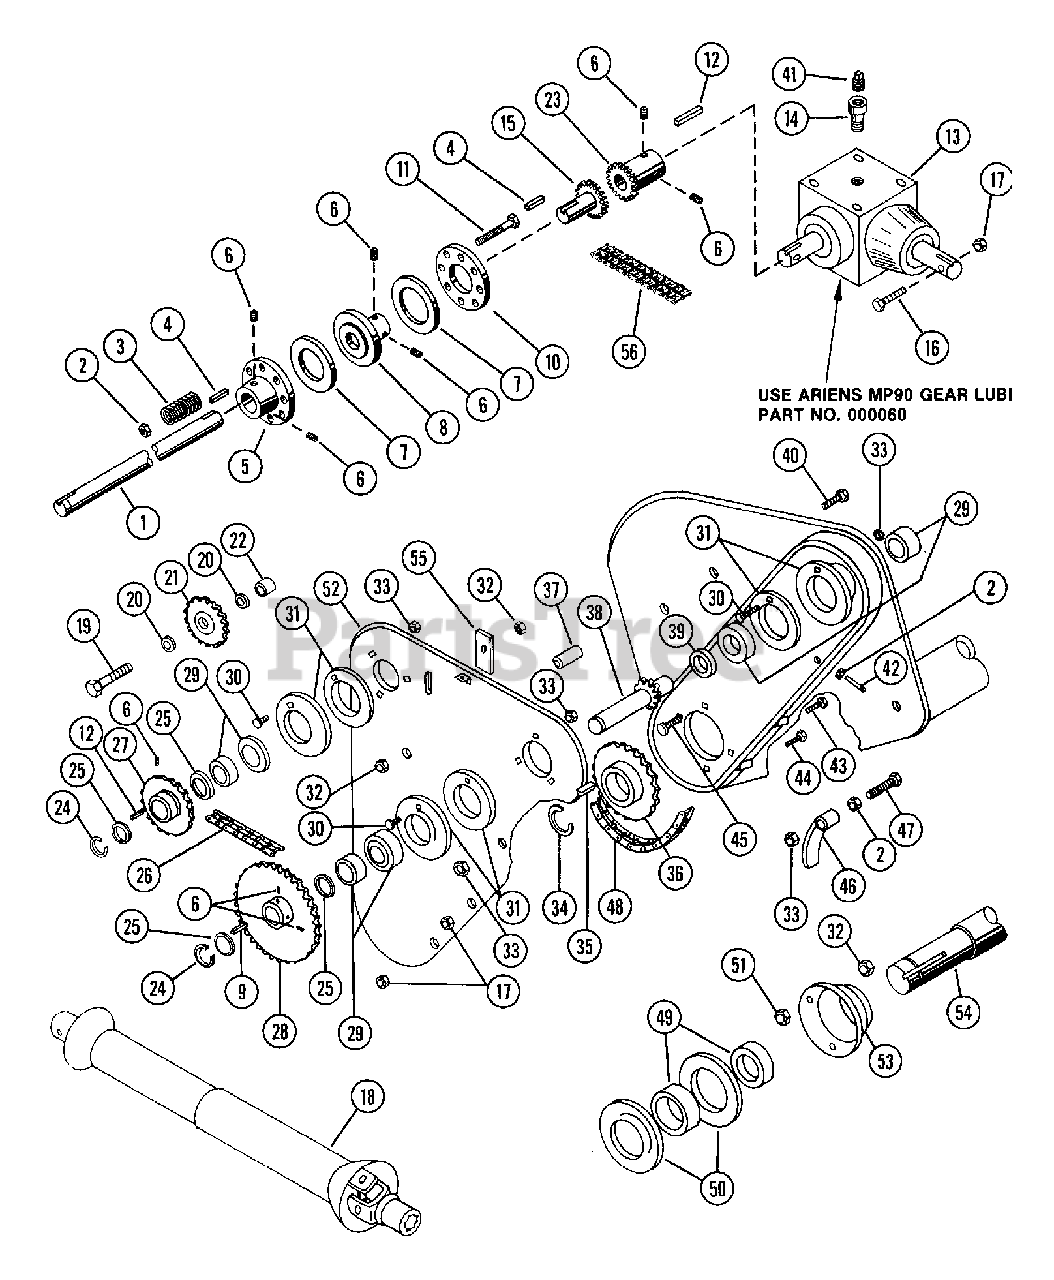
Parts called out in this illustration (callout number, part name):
1	DRIVE SHAFT
2	NUT-HEX .312-18
3	SG-COMP .135X.66X.75 WLD210
4	KEY-SQ .25 X 1.25 X .25 SAE
5	HUB-END PLATE
6	SCR-SET .32-18X.50 SKH
7	CLUTCH DISC
8	HUB-CENTER
9	KEY-SQ .25X1.0X.25 SAE 8630
10	PRESSURE PLATE
11	BLT-HEX .31-18X2.75 GR5
12	KEY-SQ .25 X 1.50 X .25 SAE
13	GEAR BOX ASSEMBLY
14	COUPLING
15	COUPLER-MALE HALF
16	BLT-HEX .38-16X2.50 PL GR5
17	NUT-LK TOP .375-16 GR C YWZC
18	UNIVERSAL DRIVE SHAFT
19	BLT-HEX .50-13X2.75 PL GR5
20	WSHR-FL-STL .505X1.000X.062
21	IDLER SPROCKET
22	SPACER-IDLER
23	COUPLER-FEMALE HALF
24	RG-RTNG-EXT 1.00X.042
25	WSHR-FL-STL 1.015X1.500X.134
26	ROLLER CHAIN
27	SPROCKET 11T
28	SPROCKET 40 T
29	BRG-BALL 1.0X2.047X.59
30	BLT-RDHDSQNK.31-18X.75GR5SHTPL
31	FLANGETTE
32	NUT-LK-CROWN .50-13 GR C PL
33	NUT-LK-TOP .312-18 GR C PL
34	RG-RTNG-EXT 1.500X.050
35	KEY-SQ .38X1.00X.375 SAE 1035
36	DRIVEN SPROCKET
37	TUBE .512 X .747 X 2.00
38	SPROCKET SHAFT
39	SPACER 1.050X1.312X.410
40	BLT-HEX .50-13X3.00 PL GR2
41	VENT PLUG
42	SCR-SET .32-18X2.00 SKHCUP
43	BLT=RDHDSQNK .38-16X2.75 GR2PL
44	CARRIAGE BOLT-SPECIAL
45	BLT-RDHDSQNK .50-13X1.50 PL
46	CHAIN TIGHTNER
47	BLT-HEX .31-18X2.75 GR2
48	DRIVE CHAIN
49	BRG-BALL 1.50X80MMX1.7
50	FLANGETTE-4 HOLE
51	NUT .50-13 PL
52	INNER COVER
53	CAP-BEARING GUARD
54	TINE SHAFT
56	CHAIN-COUPLER
